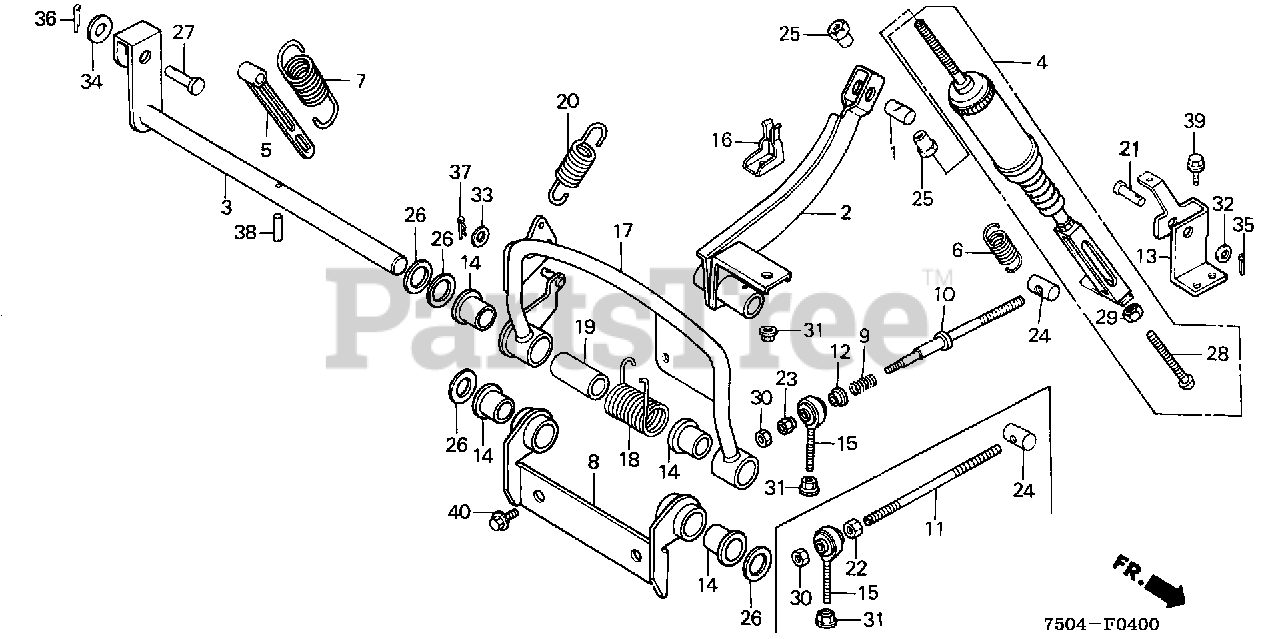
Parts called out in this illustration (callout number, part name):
1	PIN, JOINT LOCK
2	ARM, DAMPER
3	SHAFT, CLUTCH ARM
4	DAMPER ASSY.
5	ARM, STOPPER
6	SPRING, DAMPER
7	SPRING, COUNTER
8	BRACKET, R. CHANGE ARM
9	SPRING, CLUTCH ROD (NOT AVAILABLE)
10	ROD, CLUTCH ARM
12	COLLAR, CLUTCH ROD
14	BUSH (15X19X22)
15	END, ROD (NOT AVAILABLE)
16	PLATE, STOPPER
17	ARM, CLUTCH
18	SPRING, COUNTER TORSION
19	COLLAR, CLUTCH ARM
20	SPRING, ARM RETURN
21	PIN, FLAT (6X30)
23	NUT, SPECIAL (6MM)
24	NUT, TENSIONER
25	NUT, DAMPER LOCK (6MM)
26	WASHER, THRUST (15MM)
27	PIN, COUNTER (10X29)
28	SCREW, PAN (6X45)
29	NUT, HEX. (6MM)
30	NUT, HEX. (6MM)
31	NUT, FLANGE (8MM)
32	WASHER, PLAIN (6MM)
33	WASHER, PLAIN (8MM)
34	WASHER, PLAIN (10MM)
36	PIN, COTTER (2.0X15)
37	PIN, LOCK (8MM)
38	PIN, SPRING (5X20)
40	BOLT, FLANGE (8X14)
